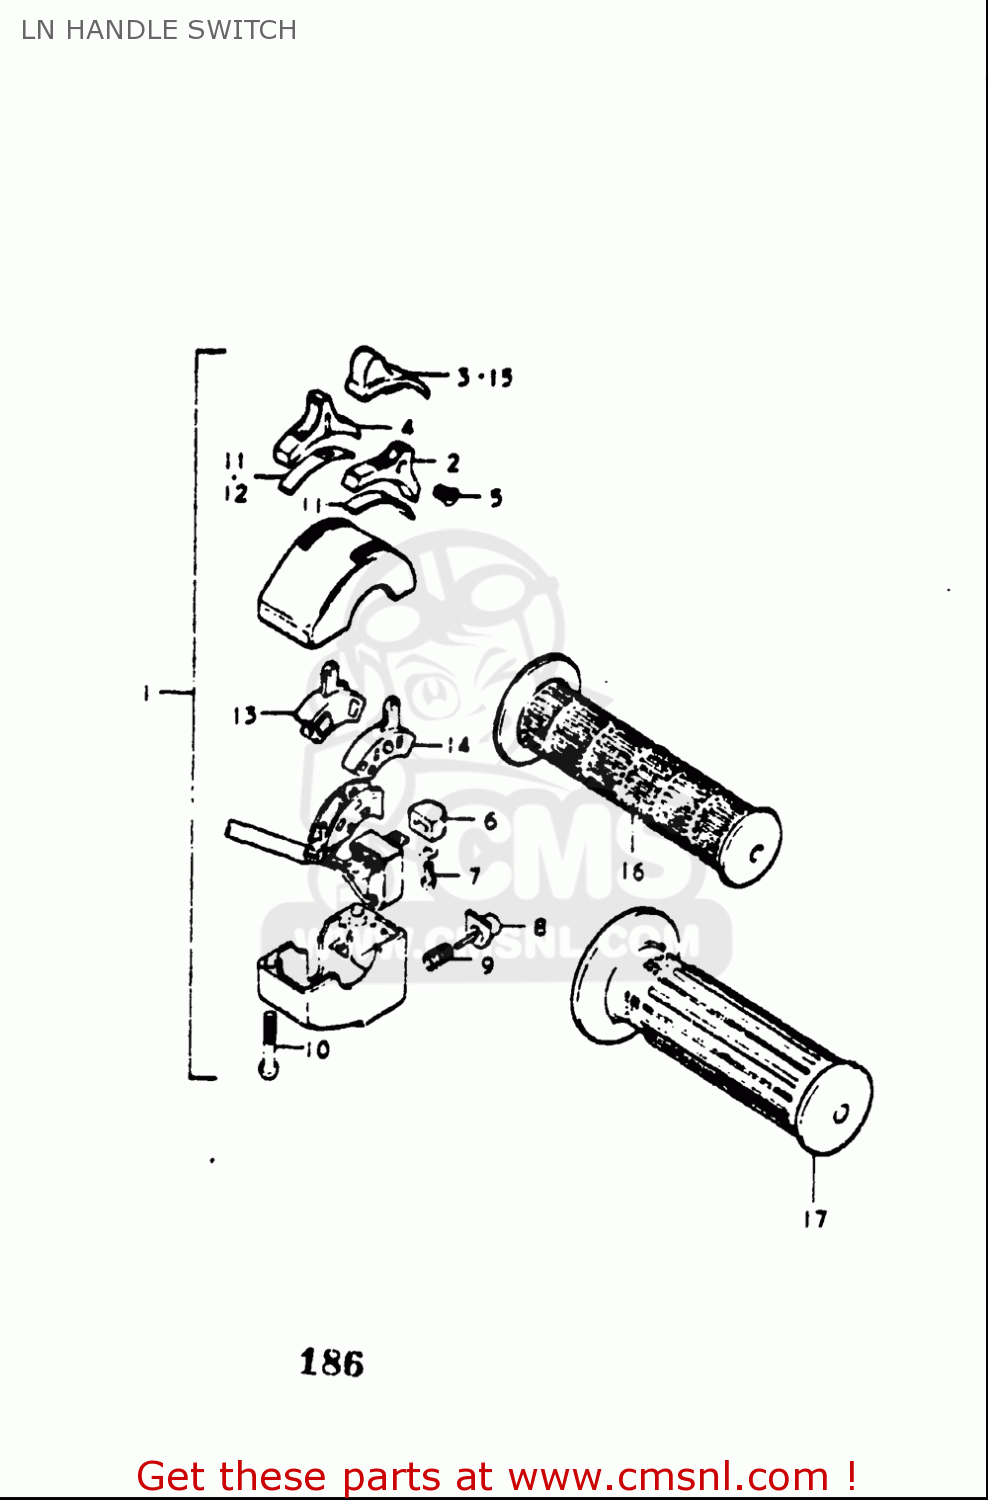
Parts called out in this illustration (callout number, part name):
2	KNOB,HANDLE SWITCH
4	KNOB
5	SCREW
7	SCREW
8	BUTTON,HORN
9	SPRING,BUTTON
10	SCREW
11	PLATE,SWITCH KNOB
14	BLOCK, LIGHTING SWITCH
16	GRIP,L
17	GRIP,L
